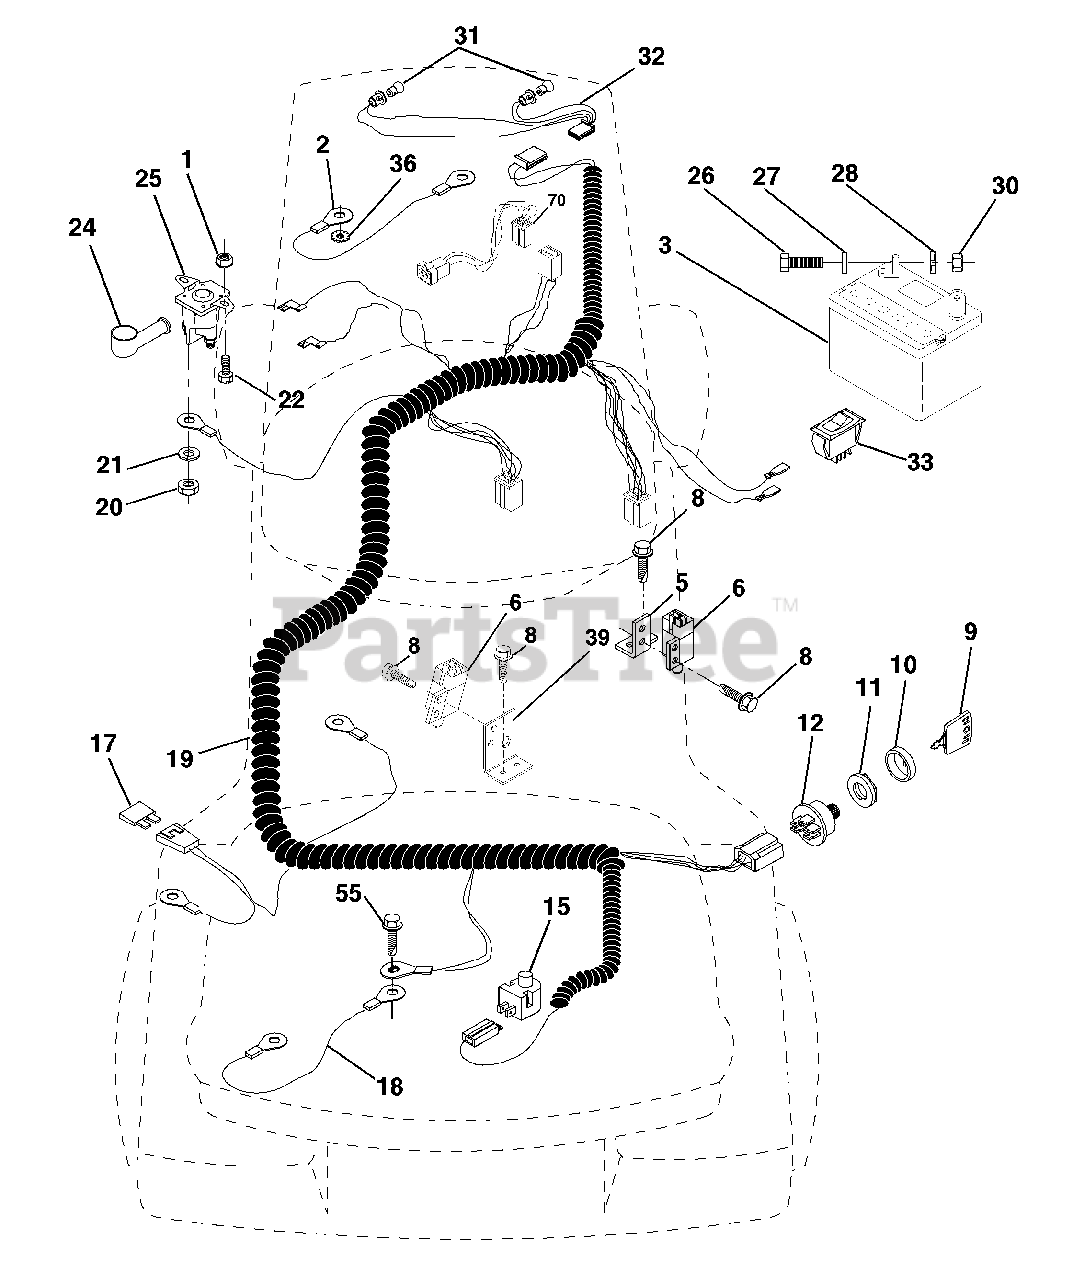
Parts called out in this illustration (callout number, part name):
1	Nut, Keps Blk Hex 1/4-20
2	Assembly, Cable
3	Battery
5	Bracket, Switch
6	Switch, Interlock, 4 Terminal
8	Screw, Hex Head, Self-Tapping #10-24 x 1/2
9	Key, Molded
10	Cover, Ignition Key
11	Nut, Ignition
12	Switch, Ignition
15	Switch, Plunger
18	Assembly, Cable
19	Harness, Ignition
20	Nut, Hex, Jam 1/4-20
21	Washer, Lock 1/4
22	Bolt, Hex, Fin. 1/4-20 UNC x 1/2 Grade 5
24	Cover, Terminal
25	Solenoid
26	Bolt, Hex Head 1/4-20 UNC x 3/4
27	Washer 9/32 x 5/8 x 16 Gauge
28	Washer, Lock 1/4
30	Nut, Hex, Fin. 1/4-20 UNC
31	Bulb, Light
32	Harness, Headlight
33	Switch, Light
36	Washer, Lock, Internal Tooth 1/4
39	Bracket, Switch Clutch
55	Screw Thdrol 5/16-18 x 1/2
70	Harness, Engine
